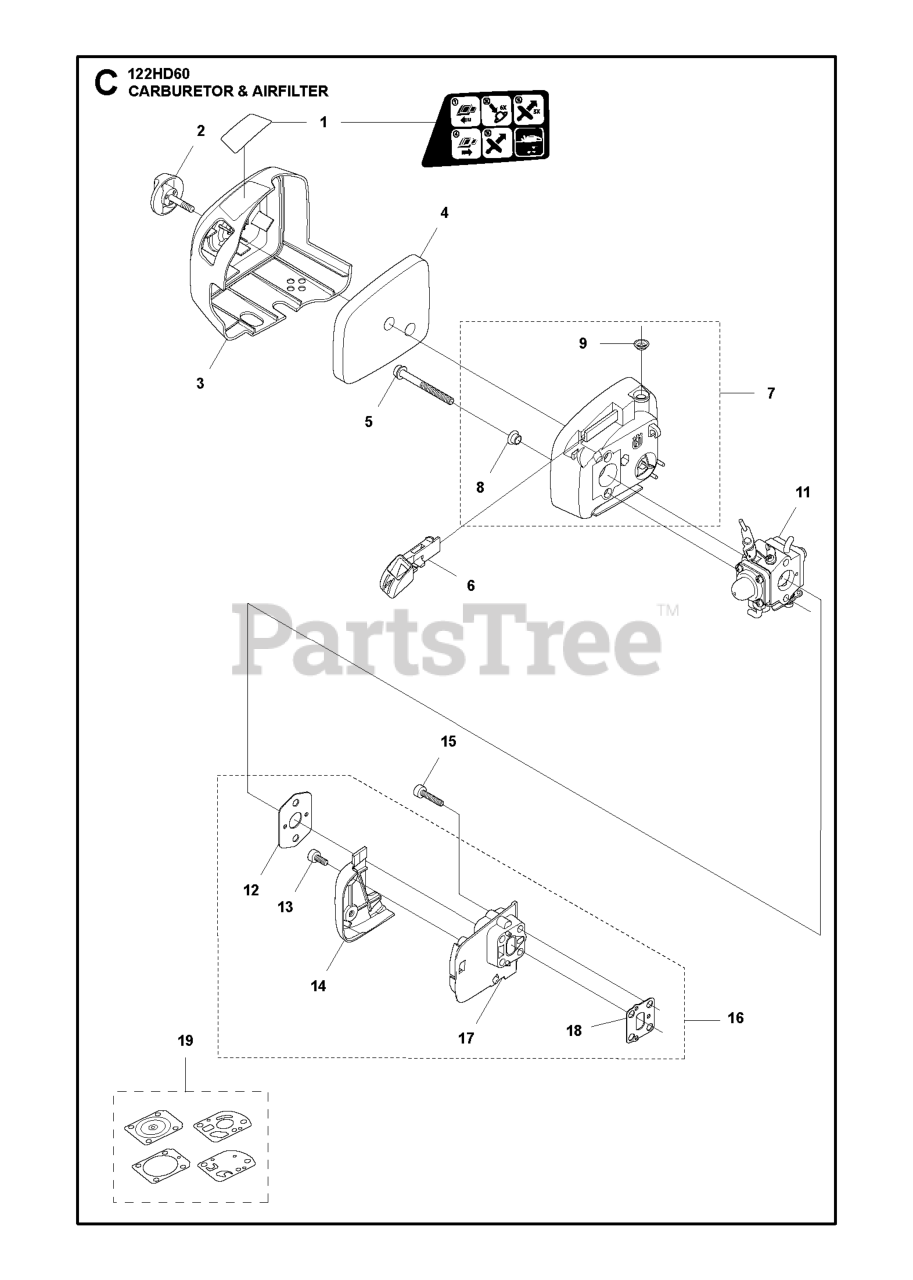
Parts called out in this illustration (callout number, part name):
3	AIR FILTER COVER
4	AIR FILTER
7	FILTER HOLDER ASSY.
8	RIVET TUBULAR
9	RIVET TUBULAR
11	CARBURETOR ASSY.
17	TUBULAR RIVET
19	KIT CARBURETTOR A053
